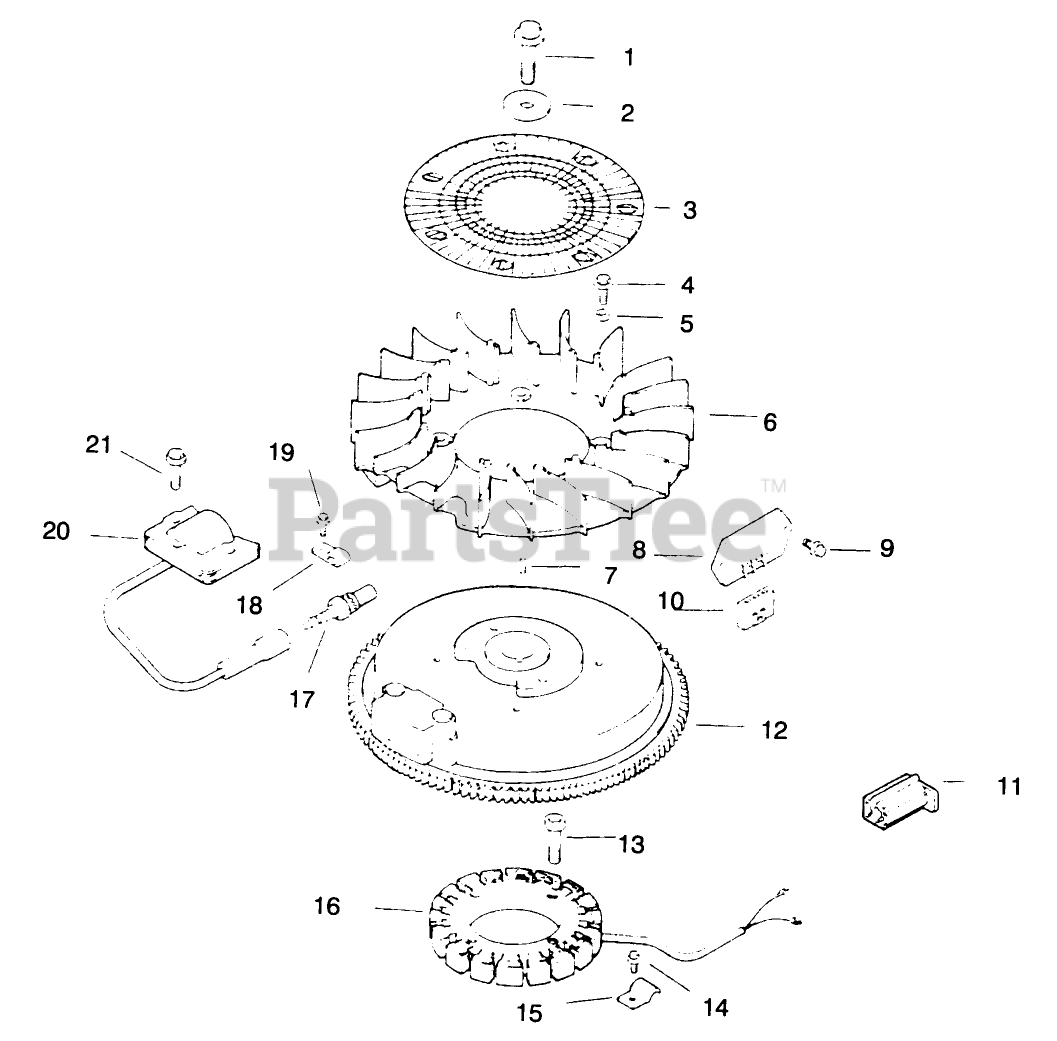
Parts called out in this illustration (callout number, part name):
1	Screw
2	Washer-Flat
3	Screen-Grass
4	Screw
5	Spacer
6	Fan
7	Key
8	Rectifier-Unregulated
9	Screw
10	Connector
11	Connector
12	Flywheel ASM
13	Screw
14	Screw
15	Clip-Stator Harness
16	Stator-15 Amp
17	Plug-Spark
18	Clip
19	Screw
20	Module-Ignition
21	Screw
